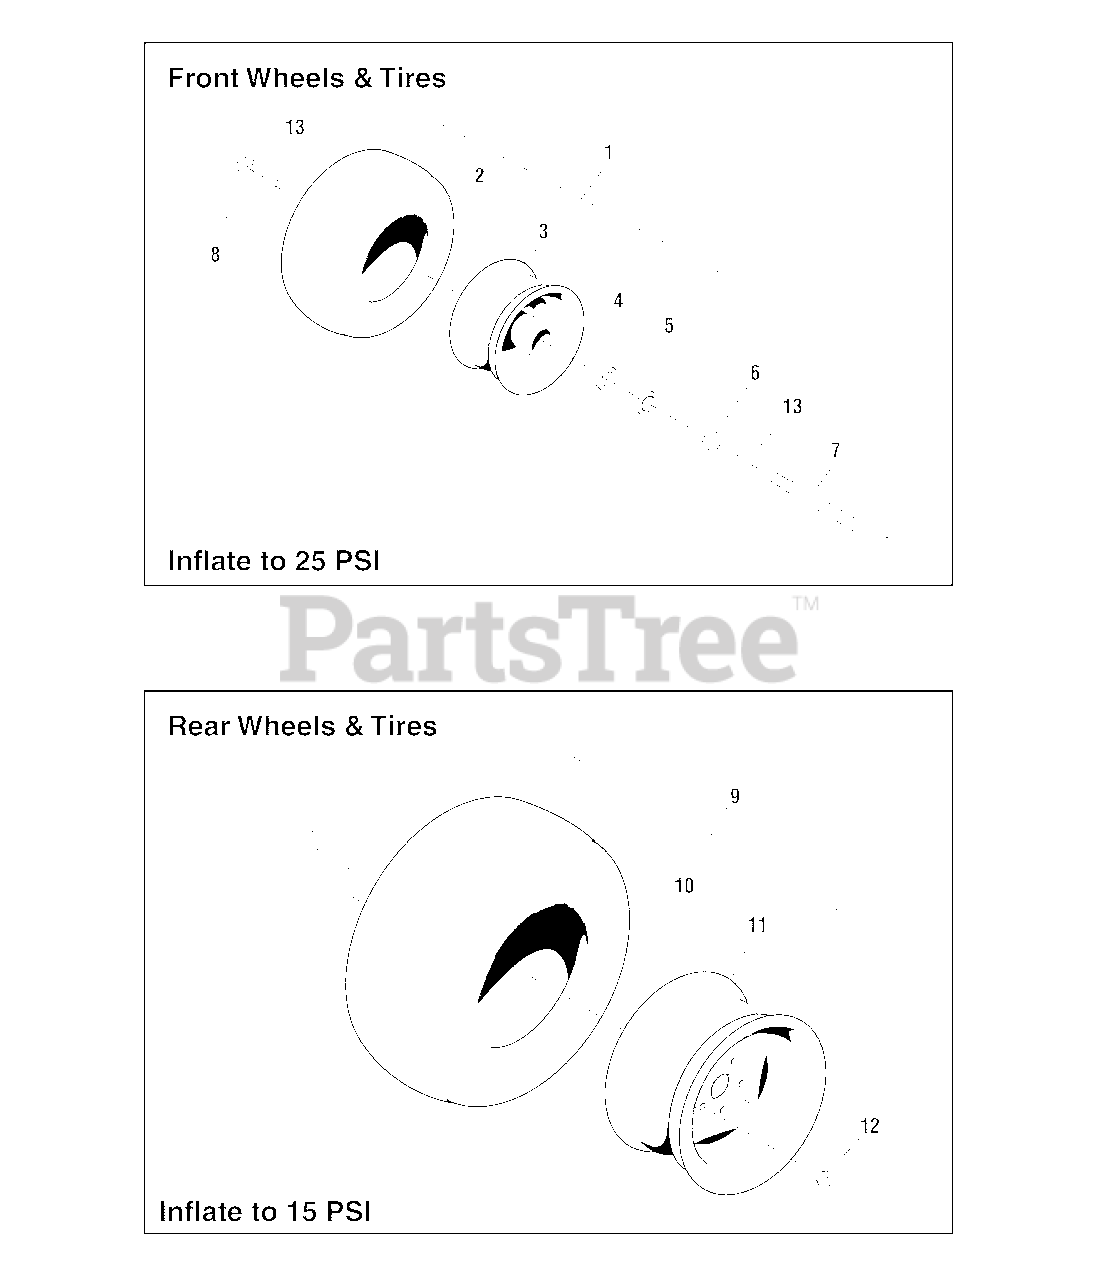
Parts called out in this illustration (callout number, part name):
2	TIRE, 13 x 5.0 - 6
3	WHEEL ASSEMBLY, for 13 x 5.0 - 6 Tire, Complete
4	BEARING, Tapered Roller
5	SEAL, GREASE
6	ADAPTER, CASTER AXLE, CZ
7	BOLT, 1/2-13 x 8"
8	NUT, 1/2-13 HEX NYLON LOCK
11	RIM-10X7-5-4.5 SOLID
12	LUG NUT, 1/2-20
13	WASHER, 1/2 SAE
